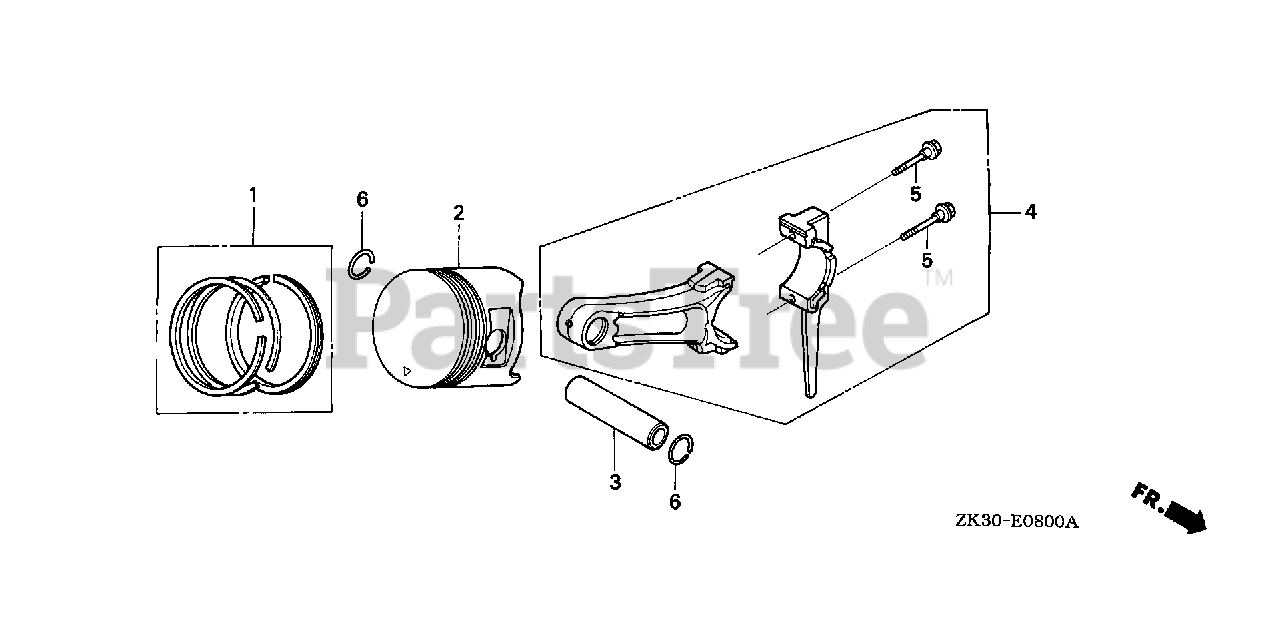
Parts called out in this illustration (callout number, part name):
1	RING SET, PISTON (STD) (NIPPON)
1	RING SET, PISTON (0.25) (NIPPON)
1	RING SET, PISTON (0.50) (NIPPON)
1	RING SET, PISTON (0.75) (NIPPON)
2	PISTON (STD)
2	PISTON (0.25)
2	PISTON (0.50)
2	PISTON (0.75)
3	PIN, PISTON
4	ROD ASSY., CONNECTING (STD)
4	ROD ASSY., CONNECTING (0.25 LOWER SIZE)
4	ROD ASSY., CONNECTING
5	BOLT, CONNECTING ROD
6	CLIP, PISTON PIN (20MM)
